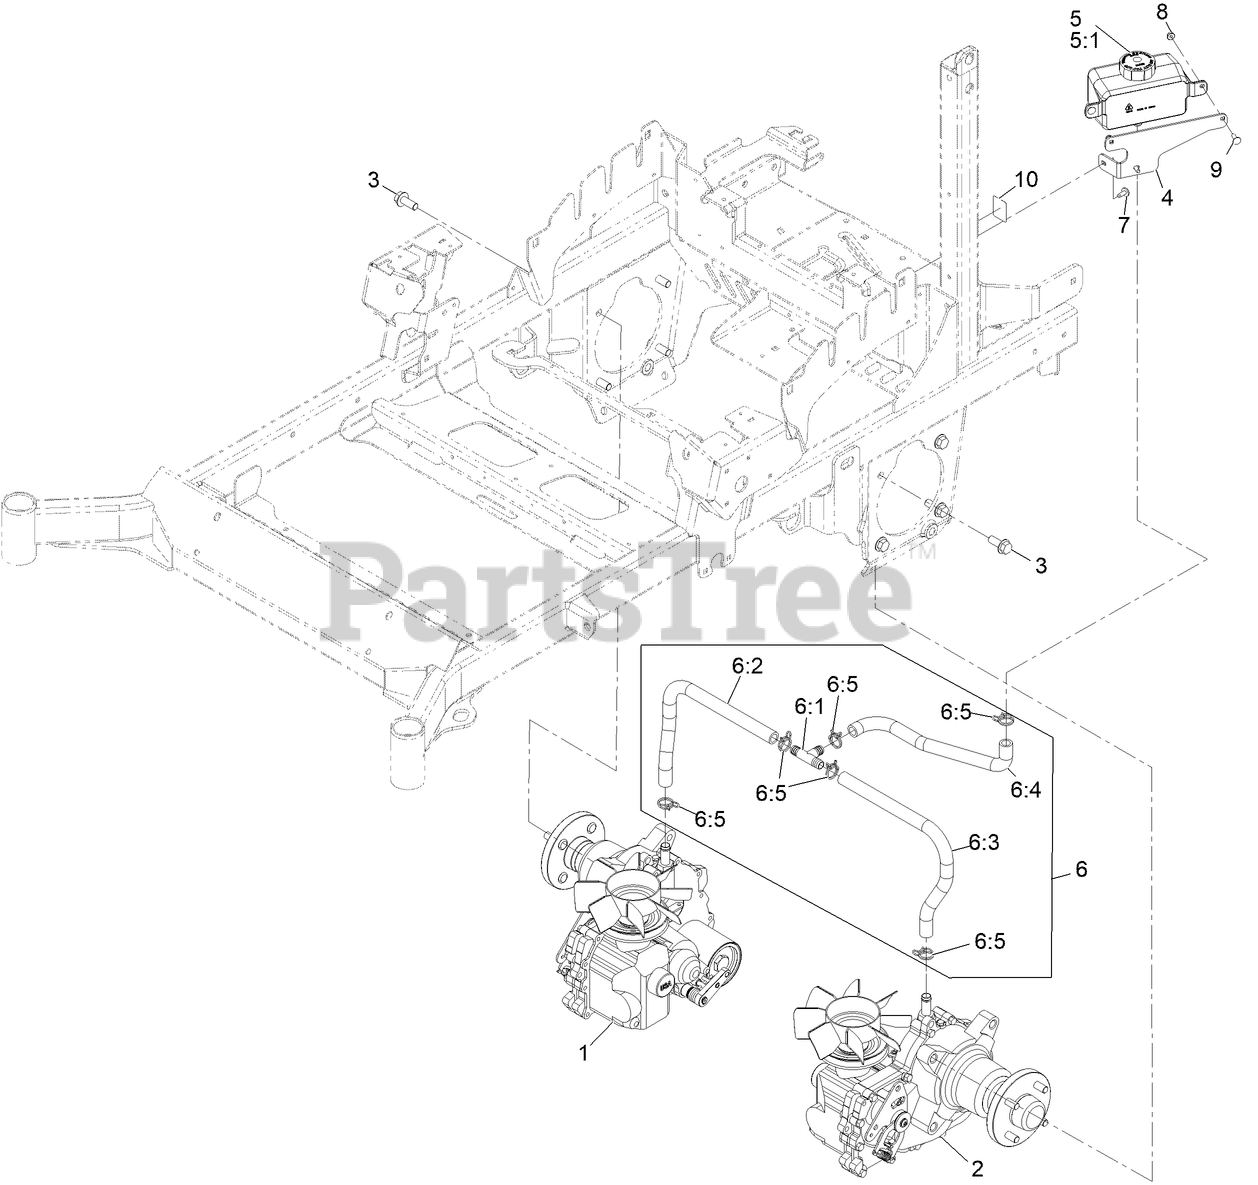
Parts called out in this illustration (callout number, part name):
1	Transaxle, Zt4400, Rt
2	Transaxle, Zt4400, Lt
3	SCREW-HHF
4	MOUNT, EXPANSION TANK
5	HYDRAULIC RESERVOIR ASM
5:1	CAP-RESERVOIR, HYD
6	ASM, Hose
6:2	Hose, Formed
6:3	Hose, Formed
6:4	Hose, Formed
6:5	CLAMP-HOSE
7	SCREW-TORX
9	BOLT-CARR
10	DECAL-HYDRO SERVICE INTERVAL
